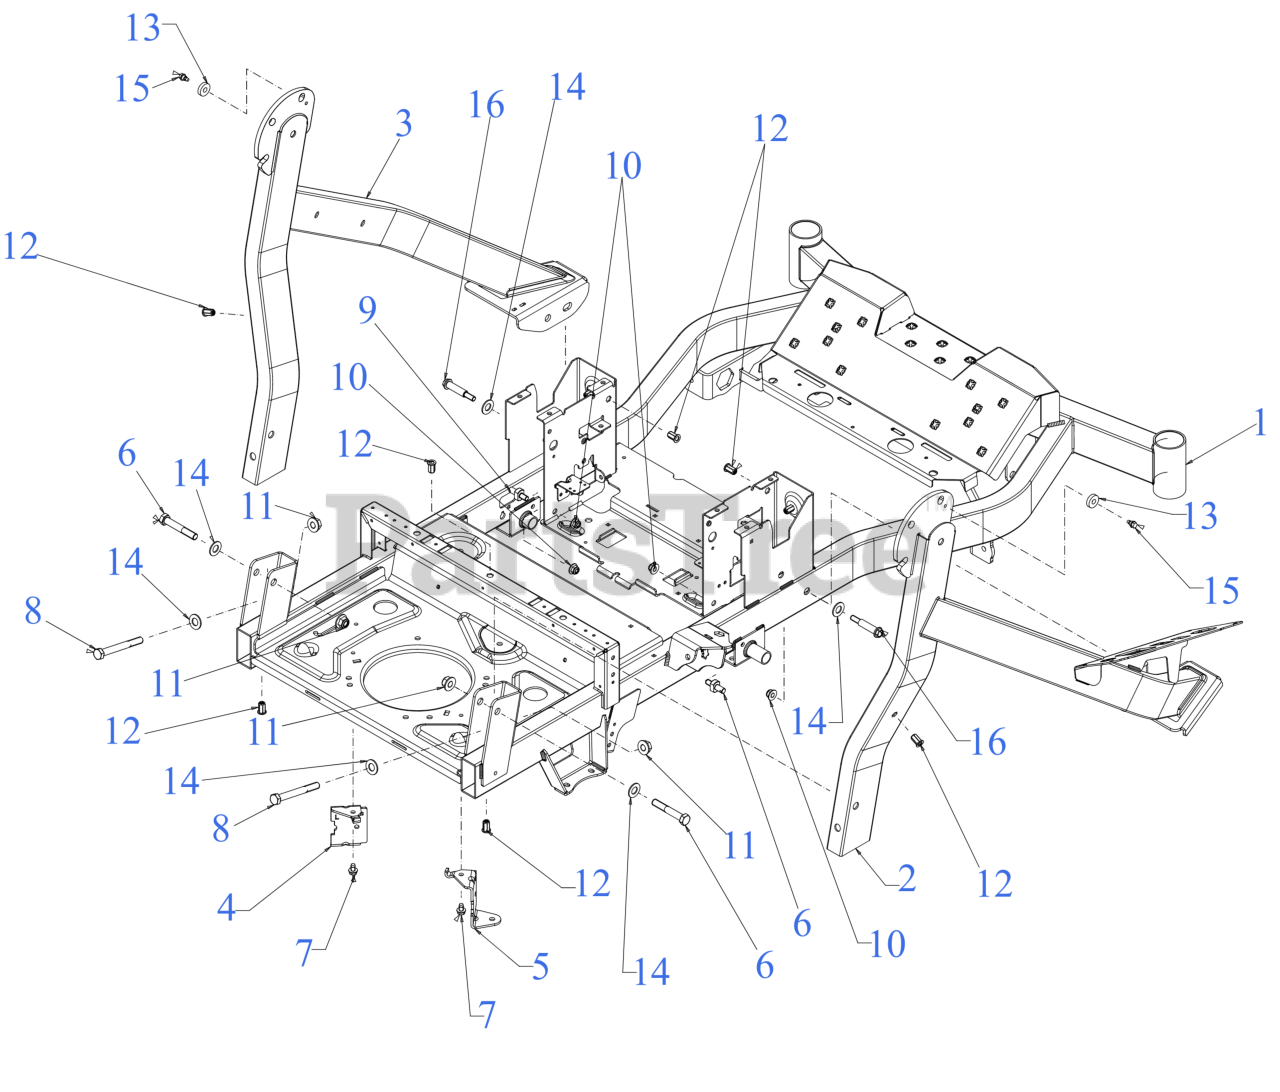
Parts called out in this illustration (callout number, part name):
1	FRAME
2	UPPER FRAME (RH)
3	UPPER FRAME (LH)
4	TRANSMISSION SUPPORT (LH)
5	TRANSMISSION SUPPORT (RH)
6	SCREW-HEX 1/2-13 x 3.00
7	SCREW 5/16-18 x .500
8	HEX CAP SCREW 1/2-13x4.25 GR5
9	SHOULDER STUD
12	NUT RIVET 5/16-18
13	NEOPRENE WASHER BUMPER
14	FLAT WASHER
15	SHOULDER SCREW 1/4-20 x .50
16	SHOULDER SCREW .50x1.75 3/8-16
